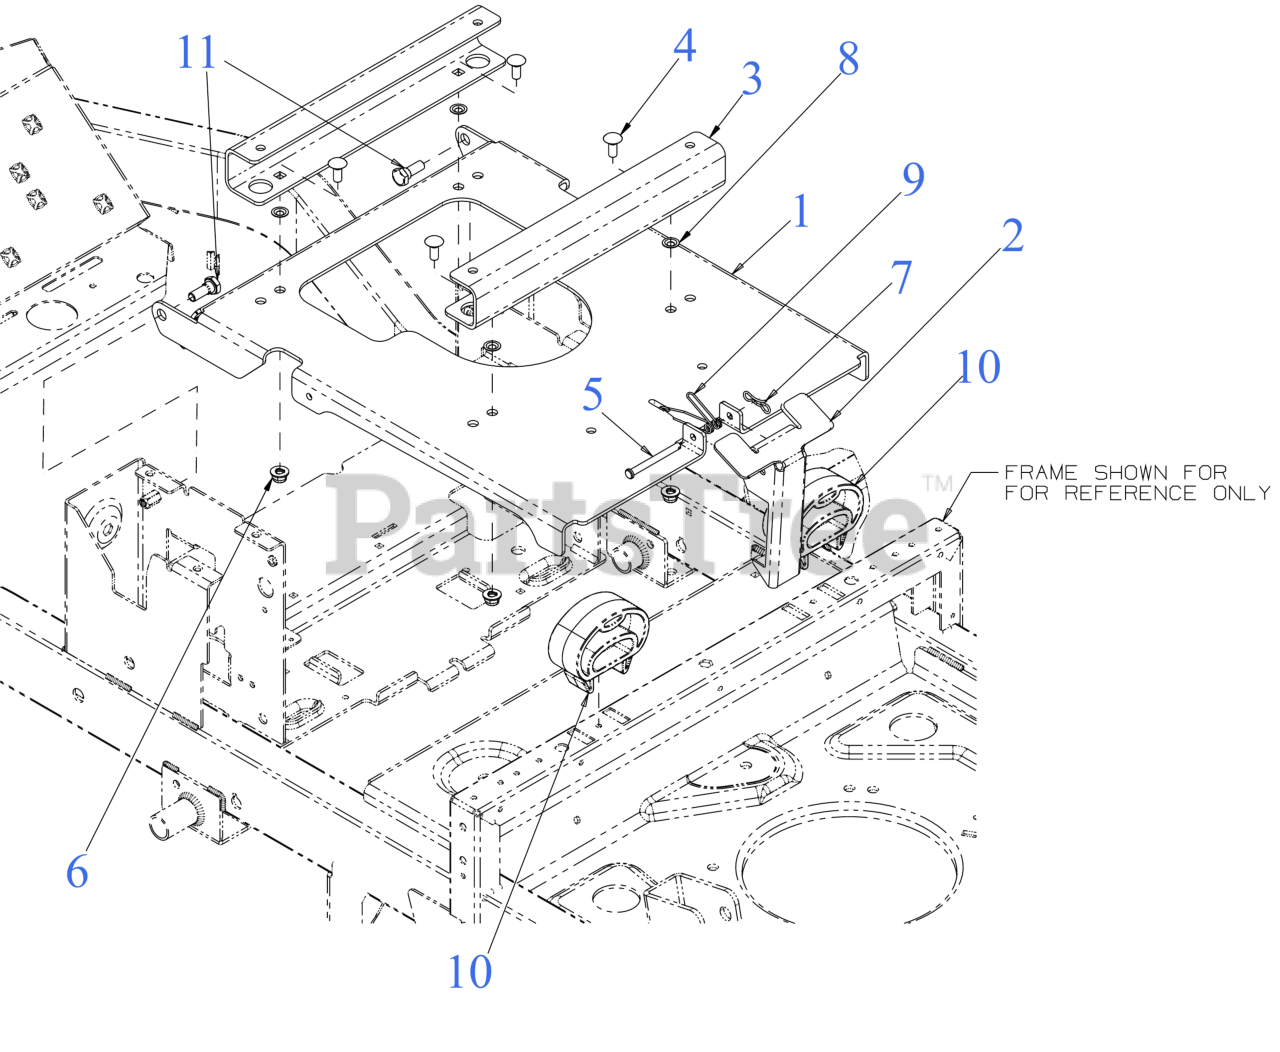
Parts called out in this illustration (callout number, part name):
1	SEAT BASEPLATE
2	SEAT LATCH BRACKET
3	SEAT SPACER BRACKET
4	CARRIAGE BOLT 5/16-18 x .75
5	CLEVIS PIN .248 x 2.345
6	FLANGE LOCK NUT 5/16-18
7	BOW TIE COTTER PIN 1/4-5/16
10	POLYMER SEAT SPRING
11	SHOULDER SCREW .437
